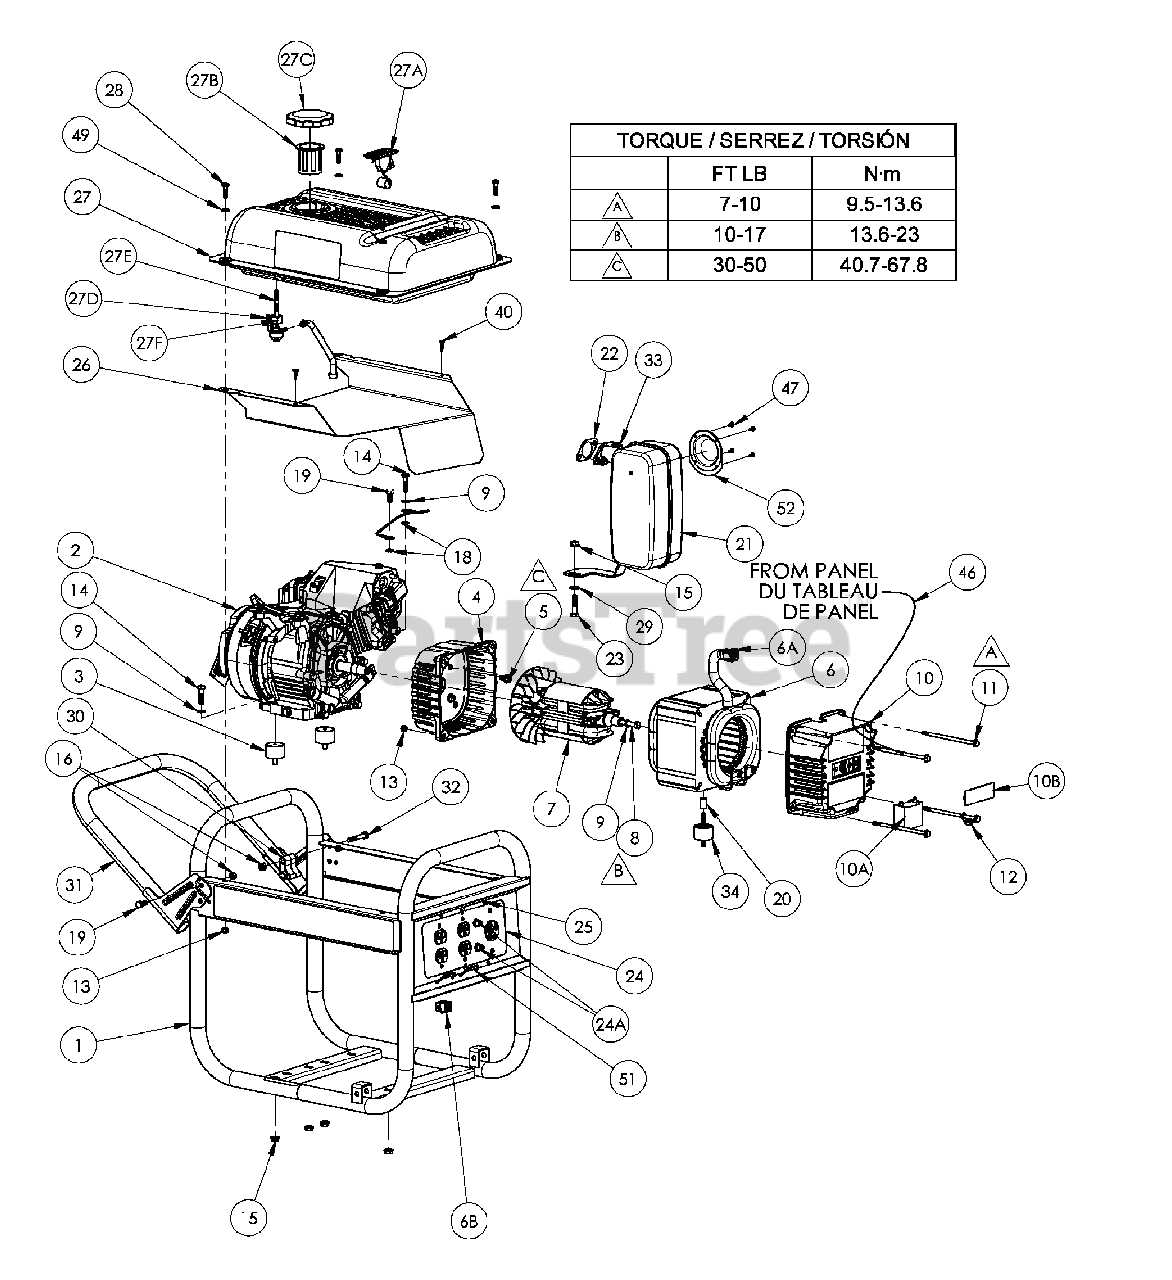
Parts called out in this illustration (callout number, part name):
1	Carrier, assembly
2	Engine Subaru OHC
3	Isolator
4	Adapter, engine
5	Bolt whz 5/16-24 x .63
6	Stator 3.5 KW 60 HZ
6A	Connector, stator
6B	Connector hsg set panel
7	Rotor 3.5 KW
8	Bolt, hex 5/16-24 x 7.75
10	Endbell Wired
10A	Capacitor
10B	Brush Cover
11	Bolt, HWH 1/4-20 x 5.50
12	Lug, ground
13	Nut, nyloc 1/4-20
15	Nut, hex flg 5/16-18
16	Nut, nyloc 5/16-18
17	Assembly, ground wire
20	Spacer .38 ID
21	Muffler
22	Gasket
24	Panel, wired
24A	Circuit Breaker 20 amp
25	Screw #6-20 x .38 Type B
26	Shield, heat
27	Fuel tank assembly
27A	Fuel Gauge/Screws
27B	Strainer Basket
27C	Fuel Cap
27D	Fuel Shut Off
27E	Filter, fuel valve and washer
27F	Nut, fuel valve
30	Spacer, handle bracket
31	Handle
33	Nut whz 8mm
34	Isolator
35	Wheel
37	Foot rubber
39	Lanyard
40	Screw, #10 x .75
42	Nut, nyloc 3/8-16
43	Spacer .38 ID
44	Pin, release
45	Cap, plastic
46	Assembly, ground wire
47	Screw HSW #8 x .38
50	Bracket, foot
51	Cord retainer
52	Screen, spark
